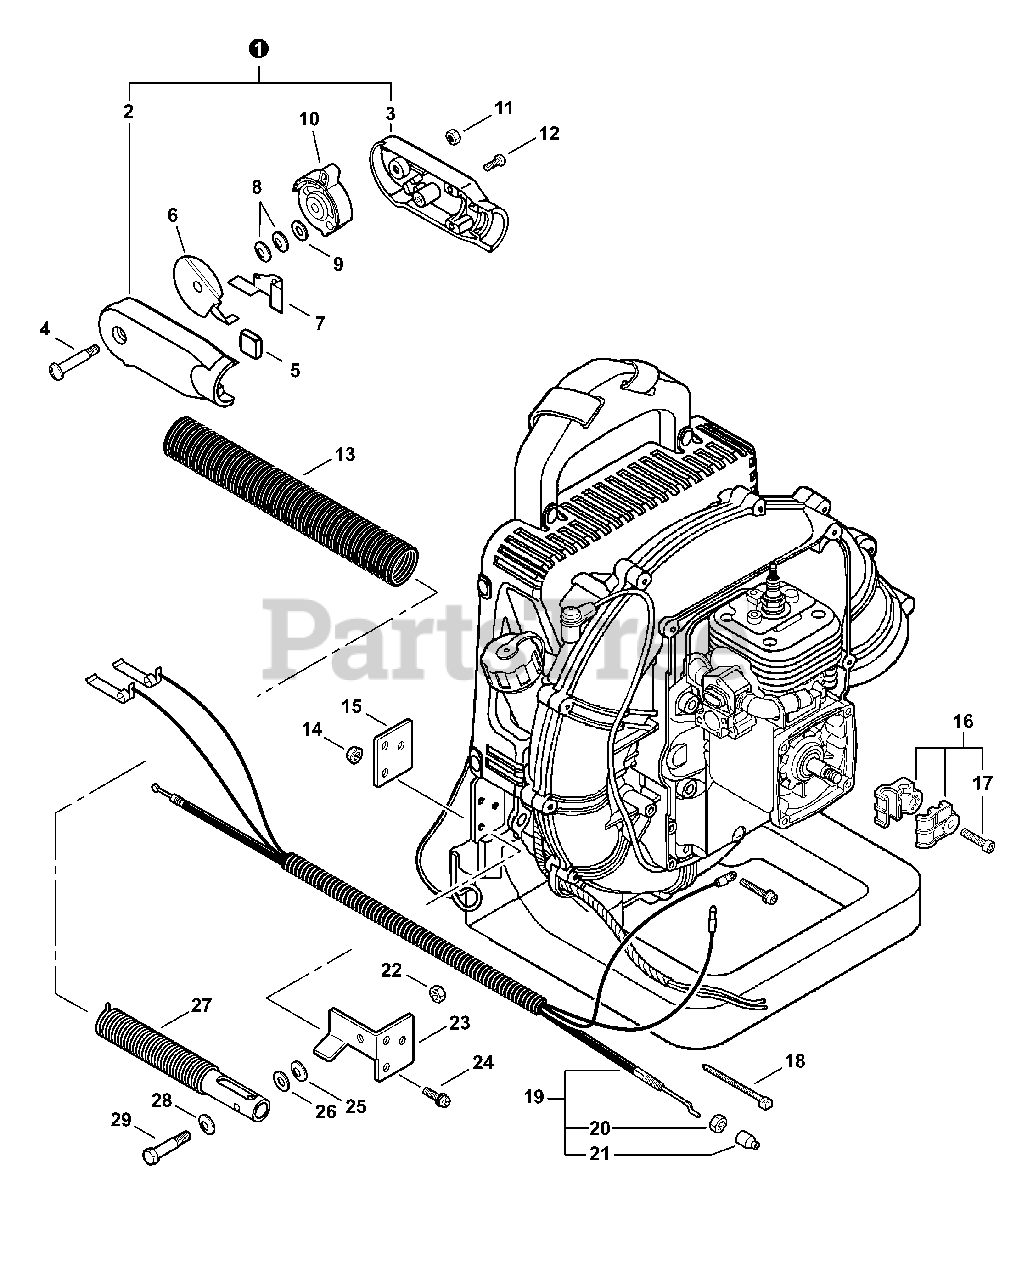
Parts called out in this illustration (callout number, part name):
1	CONTROL HANDLE ASSY
2	HANDLE, CONTROL - LEFT
3	HANDLE, CONTROL - RIGHT
4	SCREW - 4
5	PAD, FOAM
6	TERMINAL - GROUND
7	TERMINAL - GROUND
8	WASHER - SPRING
9	WASHER - 6
10	LEVER, THROTTLE CONTROL
11	LOCKNUT - 4
12	SCREW - 5×20
14	NUT - 5 -- FLANGE
16	CABLE BRACKET KIT
17	SCREW - 5×25 -- TAPPING
18	TIE, CABLE - SMALL
19	CONTROL CABLE ASSY
20	LOCKNUT - 6
21	CAP, DUST
22	LOCKNUT - 1/4"
23	BRACKET
24	SCREW - 5×18
25	WASHER - SPRING
26	WASHER - 8
27	TUBE, SPRING
28	WASHER - SPRING
29	BOLT - 6
